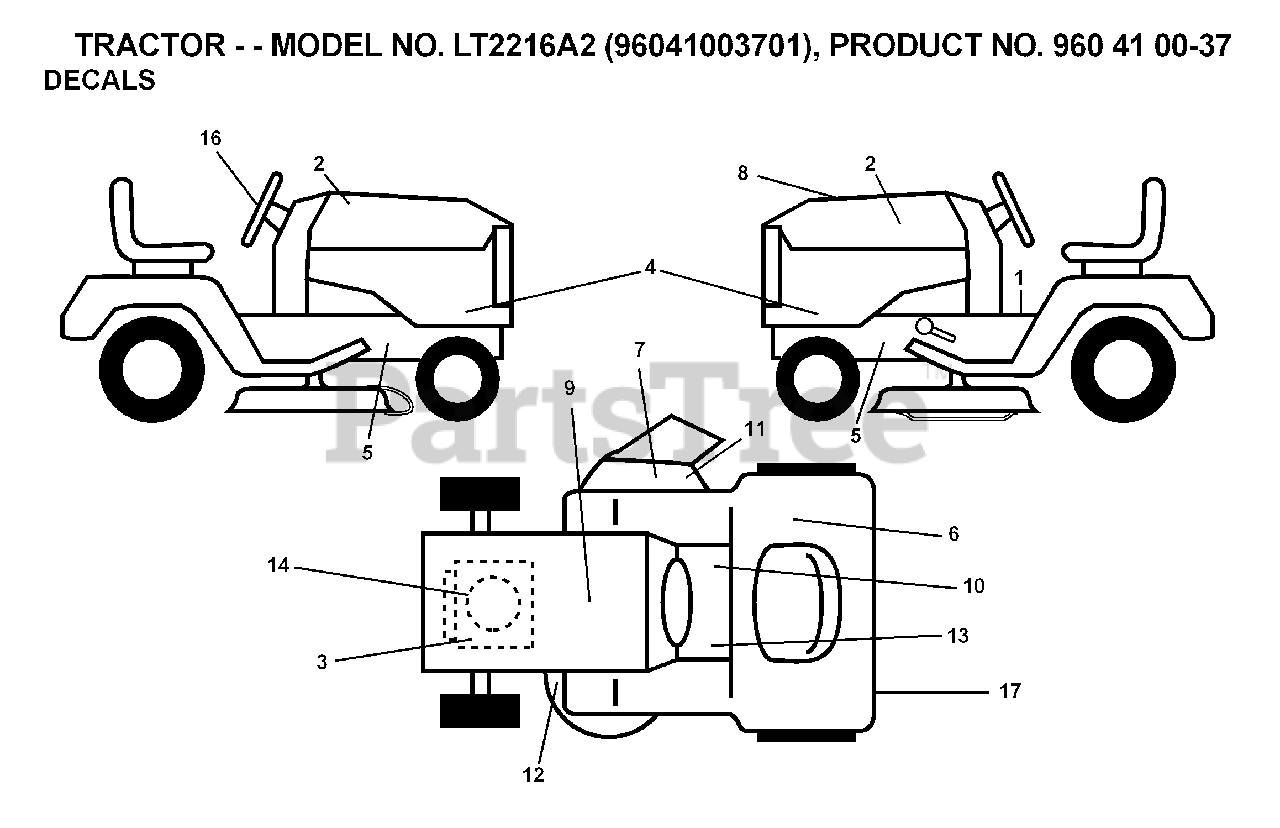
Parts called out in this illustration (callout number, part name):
7	DECAL.INTERNATIONL.CUTFINGER
9	DECAL BTRY SYMBOLS
10	DECAL PARK BRAKE
11	DECAL, DEFLECT WARNING
12	DECAL V BELT SCHEMATIC
